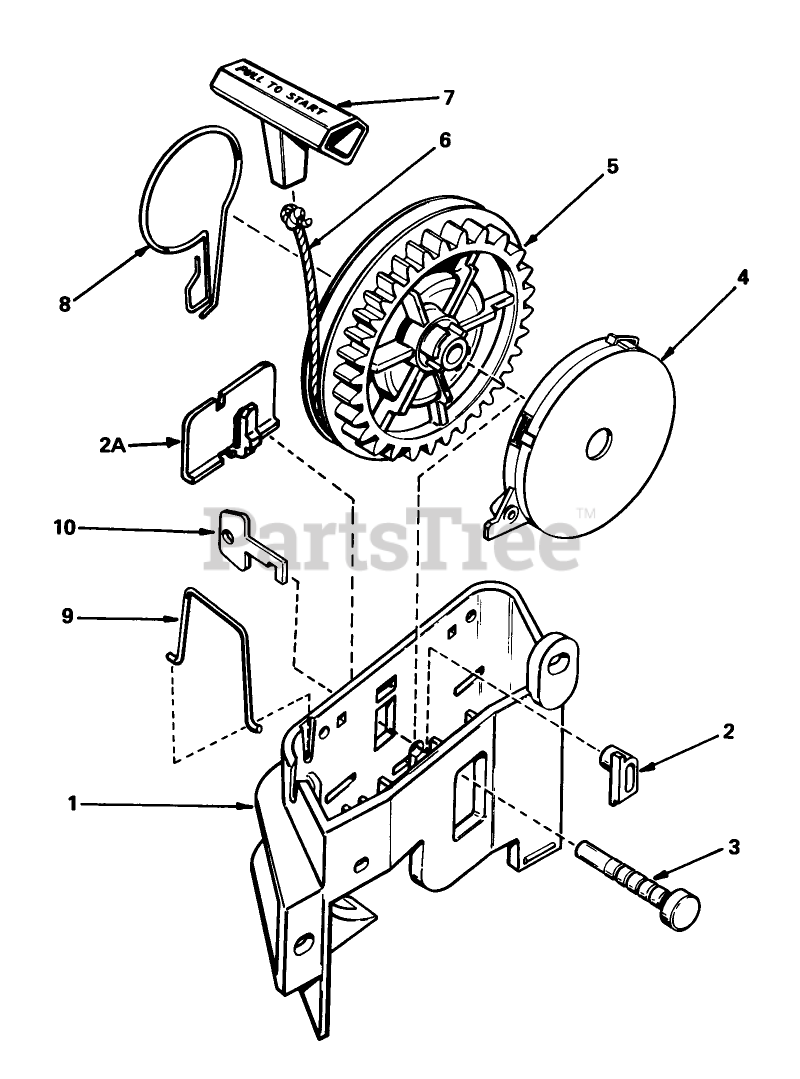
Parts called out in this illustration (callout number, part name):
1	Bracket Starter
2	Pawl, Locking Not used on all engine models)
2A	Clip, Starter Bracket (Used On Starters Not Equipped With Pawl, Ref. No. 2)
3	Pin-Pulley
4	Spring Assy., Rewind (Incl. Ref. #3)
5	Pulley
6	Rope Starter (Length 65" 9/64" Dia.)
7	Handle-Starter
8	Brake
9	Clip-Rope
10	Key (Not Used On All Engine Models
